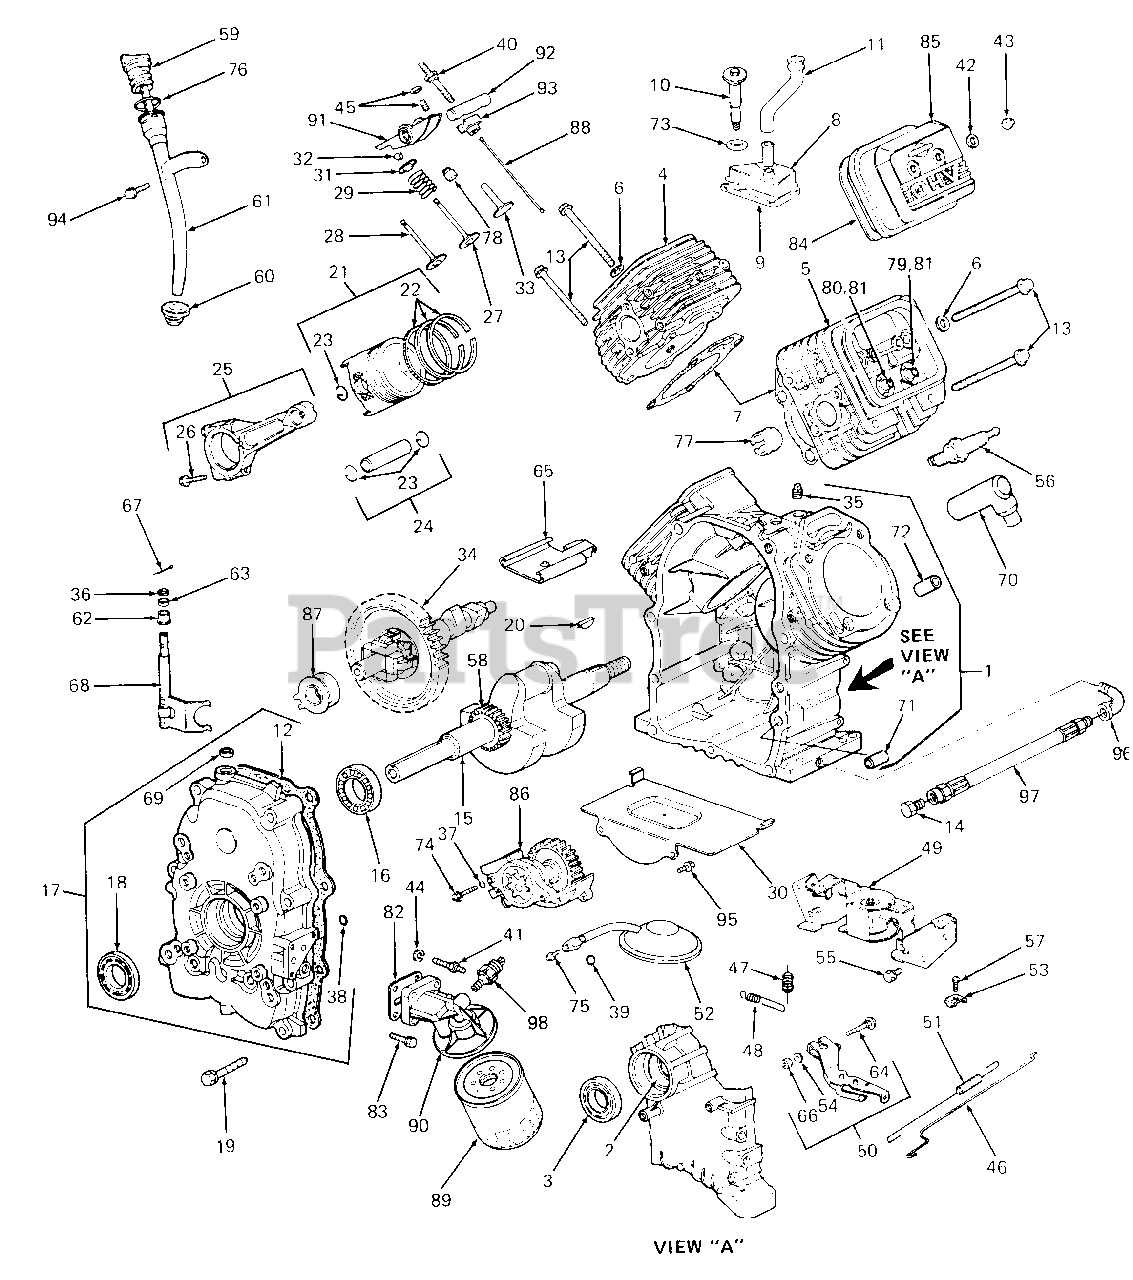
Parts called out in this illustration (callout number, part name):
1	Cylinder Assy
3	Seal, Oil
4	Head, Cylinder (Cylinder #1)
5	Head, Cylinder (Cylinder #2)
7	Gasket, Cylinder Head
8	Breather Assy
9	Gasket, Breather
10	Screw
11	Tube, Breather
12	Gasket, Cover
13	Screw
14	Plug, Oil Drain
15	Crankshaft
16	Bearing, Ball
17	Cover, Crankcase
18	Seal, Oil
19	Screw, Cover
20	Key, Flywheel
21	Piston Assy, Std
22	Ring Set, Std
23	Lock, Piston Pin
24	Pin Assy, Piston
25	Rod Assy
26	Screw, Rod
27	Valve, Exhaust
28	Valve, Intake
29	Spring, Valve
30	Plate, Windage
31	Retainer, Valve Spring
32	Retainer
33	Valve, Tappet
34	Gear, Cam
35	Plug, Pipe
36	Seal, Governor Shaft
37	O-Ring
39	O-Ring
41	Stud, Adapter
42	Washer
43	Nut, Nylock
44	Lockwasher
45	Screw, Adjustment
46	Link, Governor
47	Spring, Governor
48	Spring, Idle
49	Bracket, Governor
50	Lever Assy
51	Spring, Governor Link
52	Screen, Pick-Up
53	Clamp, Casing
55	Screw, Sems
56	Plug, Spark
57	Screw, Hex Hd
58	Gear, Timing
59	Dipstick
60	Seal
61	Tube, Filler
65	Baffle, Breather
66	Nut, Hex
67	Pin, Cotter
68	Fork, Governor
69	Washer
70	Elbow, Spark Plug
73	Seal, Screw
74	Screw, Sems
75	Screw, Mounting
76	O-Ring
77	Liner, Exhaust Port
78	Seal, Valve Guide
79	Seat, Intake Valve
80	Seat, Exhaust Valve
81	Guide, Valve
82	Gasket, Adapter
83	Screw, Sems
84	Gasket, Valve Cover
85	Cover, Valve LH
86	Oil Pump Assy
87	Slider, Governor
88	Rod, Push
89	Filter, Oil
90	Adapter, Filter
91	Arm, Rocker
94	Screw, Mounting
95	Screw, Sems
96	Elbow, 90 Deg
97	Hose, Oil Drain
98	Switch, Oil Pressure
